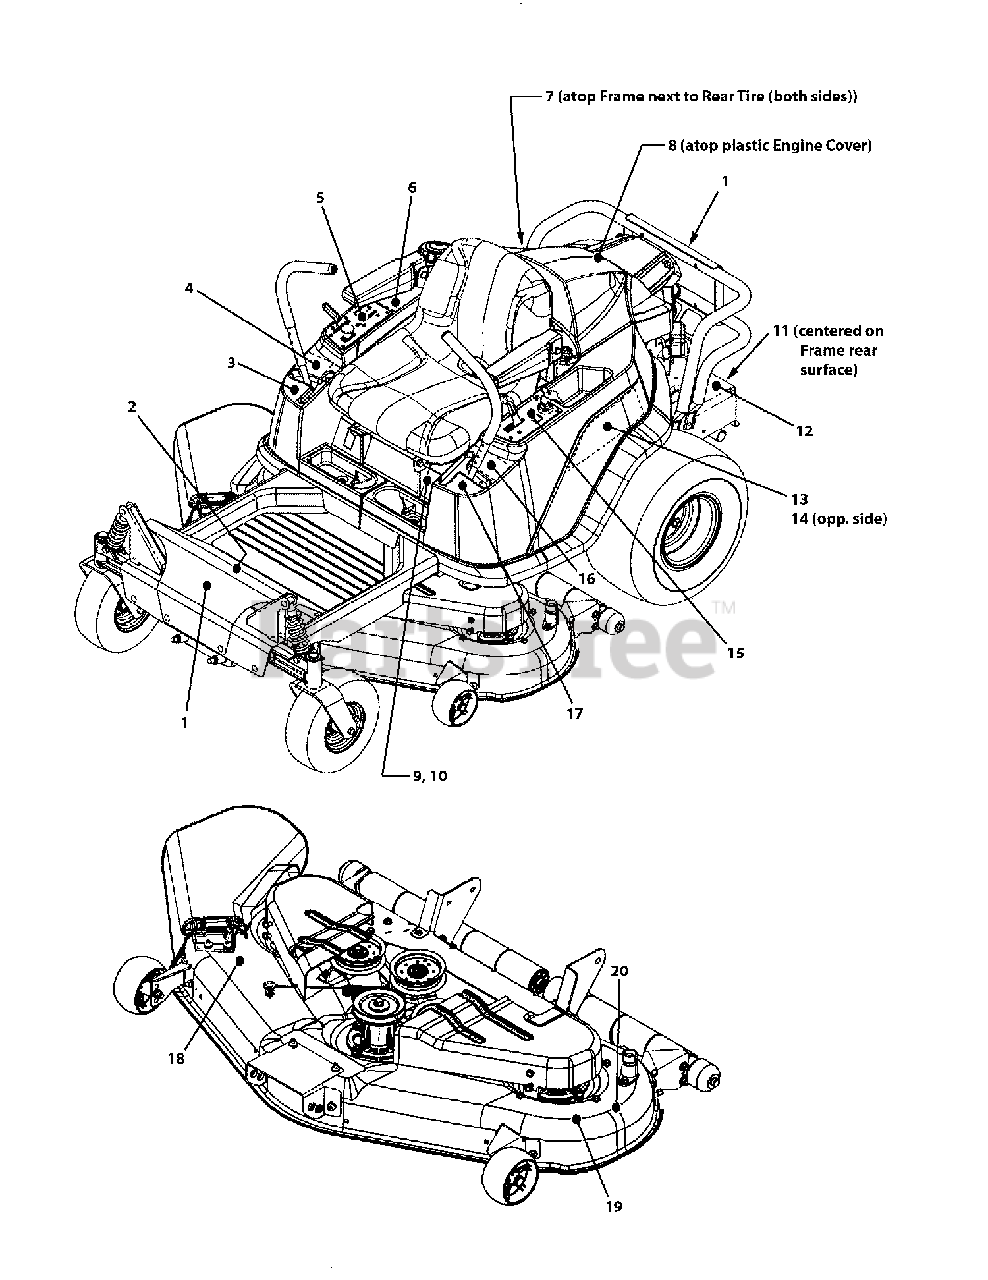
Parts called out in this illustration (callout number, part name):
1	DECAL, Simplicity Logo, Silver & Blue, Icon
1	DECAL, Massey Logo
1	DECAL, Massey Logo, 12.5
2	DECAL, Instructional, 285Z w/EFM
2	DECAL, Instructional, 285Z
3	DECAL, Handle, Ground Speed, RH, 285Z
4	DECAL, Safety, Symbol, 285Z
5	DECAL, Control Panel, RH 285Z w/EFM
5	DECAL, Control Panel, RH 285Z
6	DECAL, DANGER, English, 285Z
7	DECAL, Release, Transaxle, 285Z
8	DECAL, CAUTION, Screen Rotating
9	DECAL, Model, Simplicity ZT2000, 27 HP
9	DECAL, Model, Massey 2300, 27 HP
9	DECAL, Model, Massey 2300, 26 HP
10	DECAL, Model, Simplicity ZT2000, 26 HP
11	DECAL, Weight Limitation
12	DECAL, WARNING, Burn Hazard
13	DECAL, Fender, LH, Simplicity Logo
13	DECAL, Fender, LH & RH, Massey Logo
14	DECAL, Fender, RH, Simplicity Logo
15	DECAL, Control Panel, LH 285Z w/Hour Meter
15	DECAL, Control Panel, LH 285Z
16	DECAL, WARNING, English, LH, 285Z
17	DECAL, Handle, Ground Speed, LH, 285Z
18	DECAL, DANGER Do Not Operate w/o Deflector
19	DECAL, DANGER Do Not Put Hand/Feet in Mower
20	DECAL, 46" Deck
20	DECAL, 52" Deck (Simplicity)
20	DECAL, 52" Deck (Massey)
